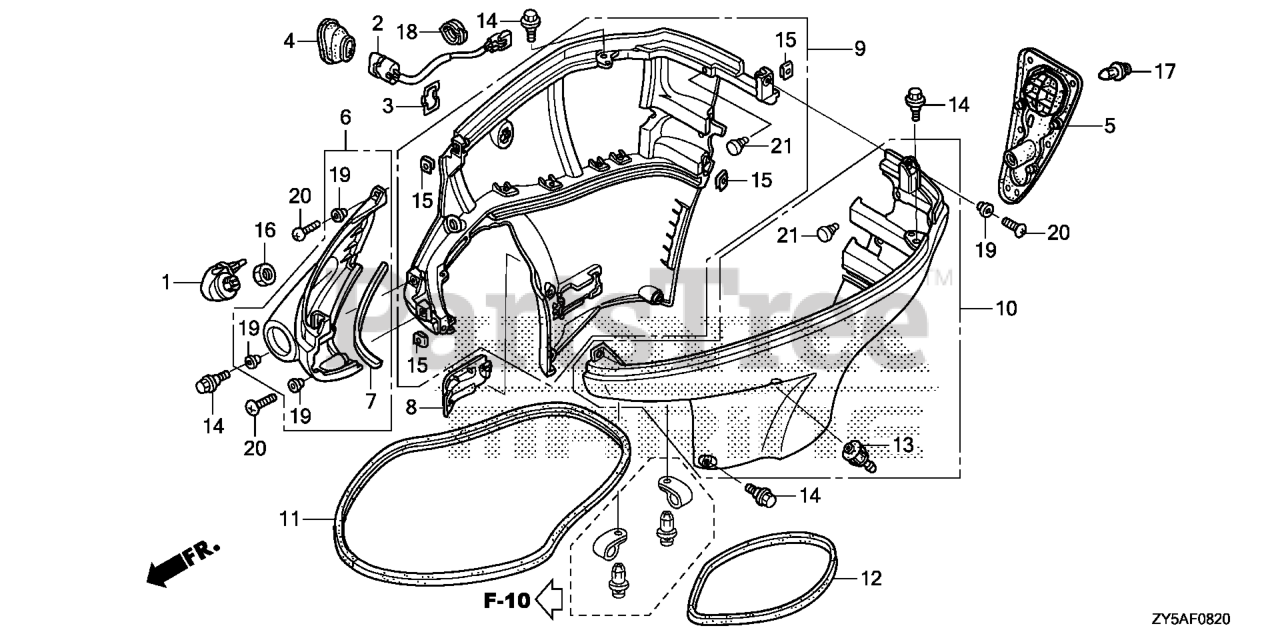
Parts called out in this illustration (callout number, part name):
1	CAP, WATER JOINT
2	SWITCH ASSY., POWER TILT
3	STAY, POWER TILT SWITCH
4	GROMMET, POWER TILT SWITCH
5	GROMMET, COVER (LOWER)
6	COVER, FR. SEPARATE *NHB14M* (AQUA MARINE SILVER METALLIC)
6	COVER,SEPAR*NH565*
7	SEAL, FR. SEPARATE COVER
8	COVER, DRAIN PLUG *NHB14M* (AQUA MARINE SILVER METALLIC)
8	COVER,DRAIN*NH565*
9	COVER, R. ENGINE (LOWER) *NHB14M* (AQUA MARINE SILVER METALLIC)
9	COVER COMP*NH565*
10	COVER, L. ENGINE (LOWER) *NHB14M* (AQUA MARINE SILVER METALLIC)
10	COVER COMP*NH565*
11	SEAL A, COVER (LOWER)
12	SEAL B, COVER (LOWER)
13	GROMMET, WATER CHECK
14	BOLT, SPECIAL (6X17)
16	NUT, HEX. (16MM) DUAL QTY = (2) (SINGLE)
17	CLIP, SPLASH GUARD
18	CLIP, WIRE HARNESS
19	COLLAR, DISTANCE (6.5X9X11.5)
20	SCREW, PAN (6X25)
21	RUBBER B, STAND STOPPER
